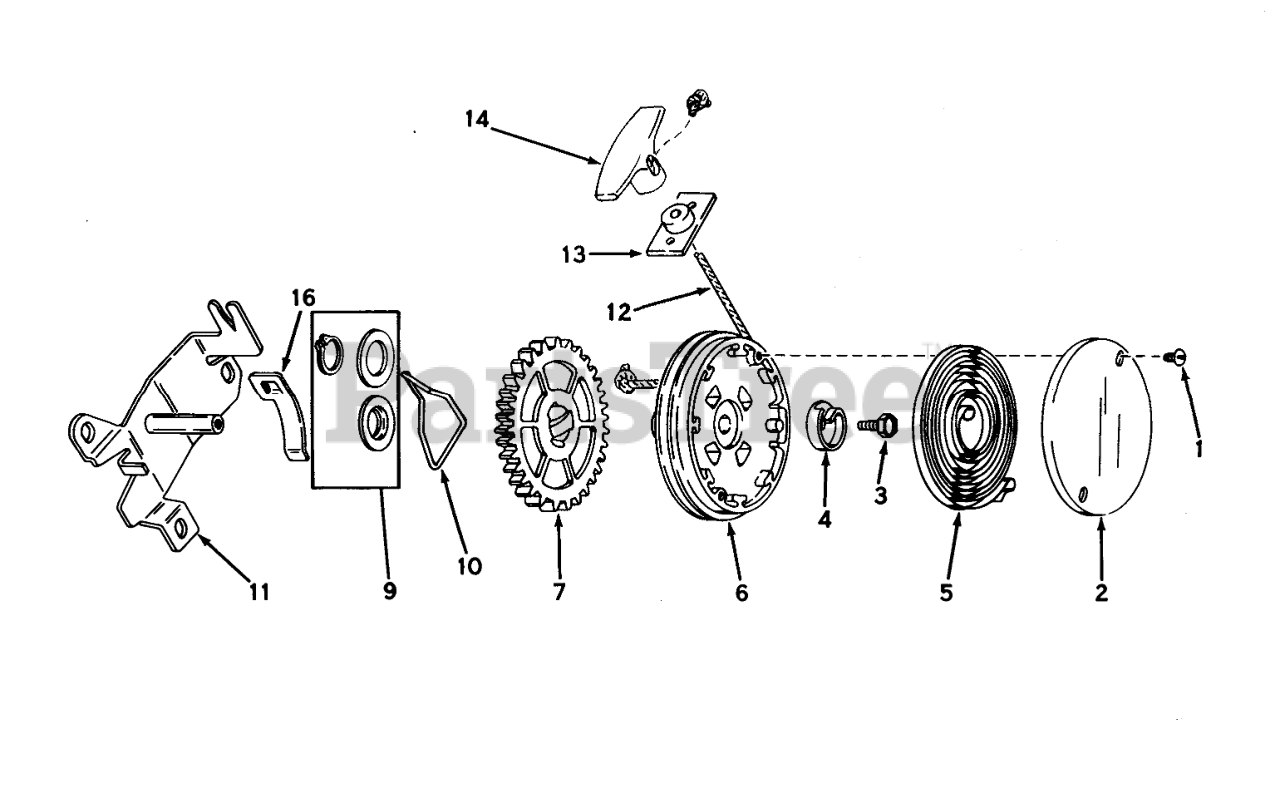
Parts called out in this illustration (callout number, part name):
2	Cover, Spring
3	Screw, Hex Washer Head
4	Hub Spring
5	Spring, Rewind
6	Pulley Assy. (Incl. Ref. #9)
9	Kit, Thrust Wash. & Snap Rg.
11	Bracket Assy. Mounting
12	Rope-Starter
13	Bracket Assy.
14	Handle-Starter
16	Clip Rope
